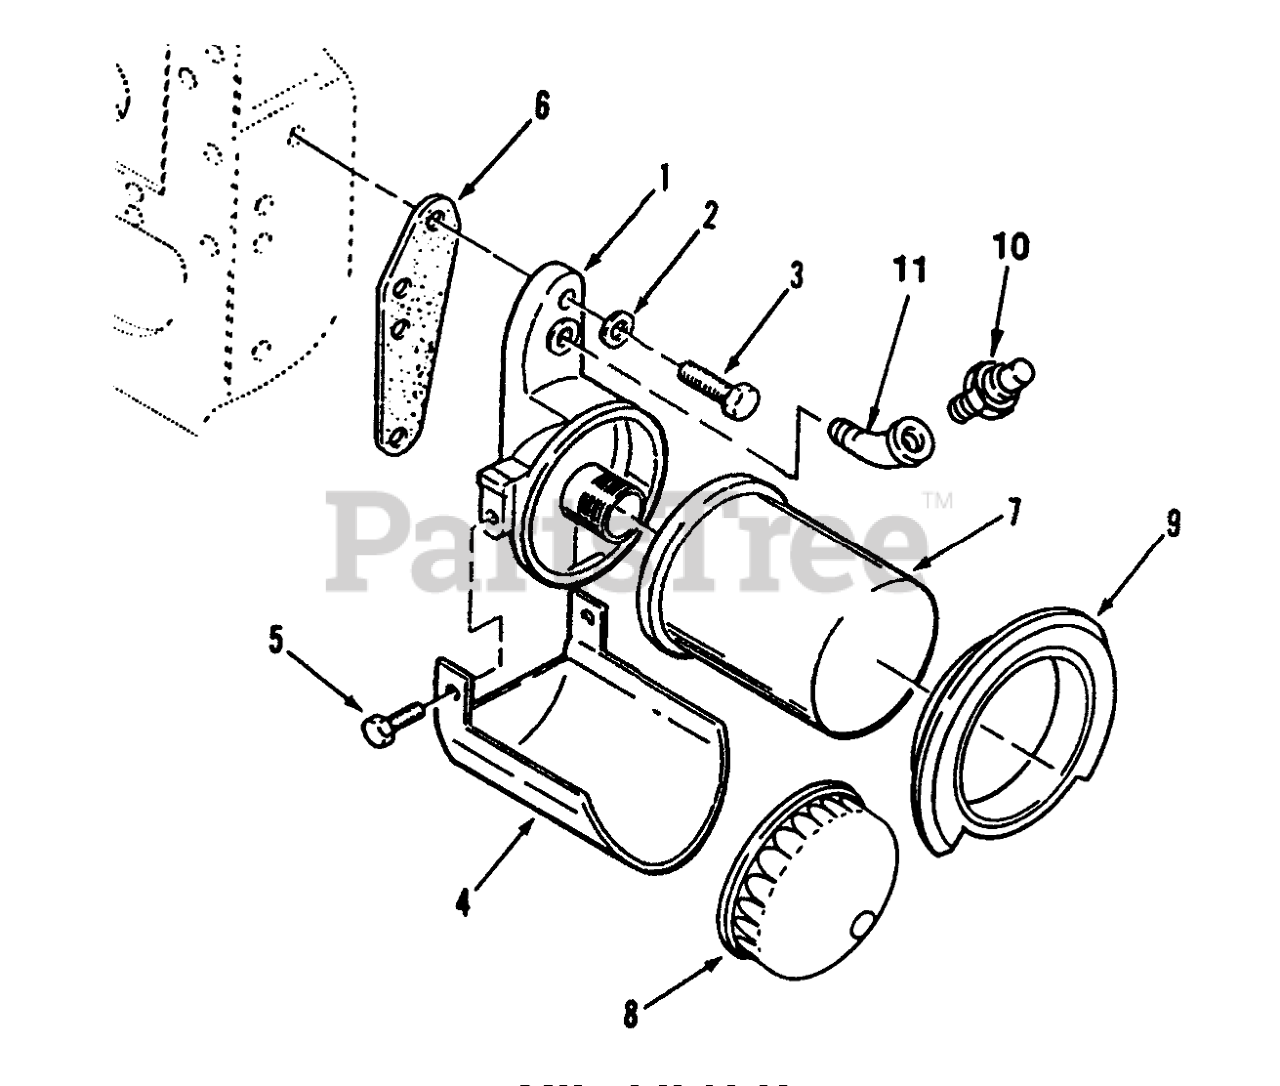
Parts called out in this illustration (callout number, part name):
1	ADAPTER-OIL FILTER
2	WASHER
3	HHCS 5/16-18 X 1
4	OIL-FILTER DRAIN
5	SCREW-HH
6	Gasket
7	OIL FILTER
8	Wrench
9	GASKET - AIR SEAL
10	SWITCH
11	45 DEG STREET ELBOW
